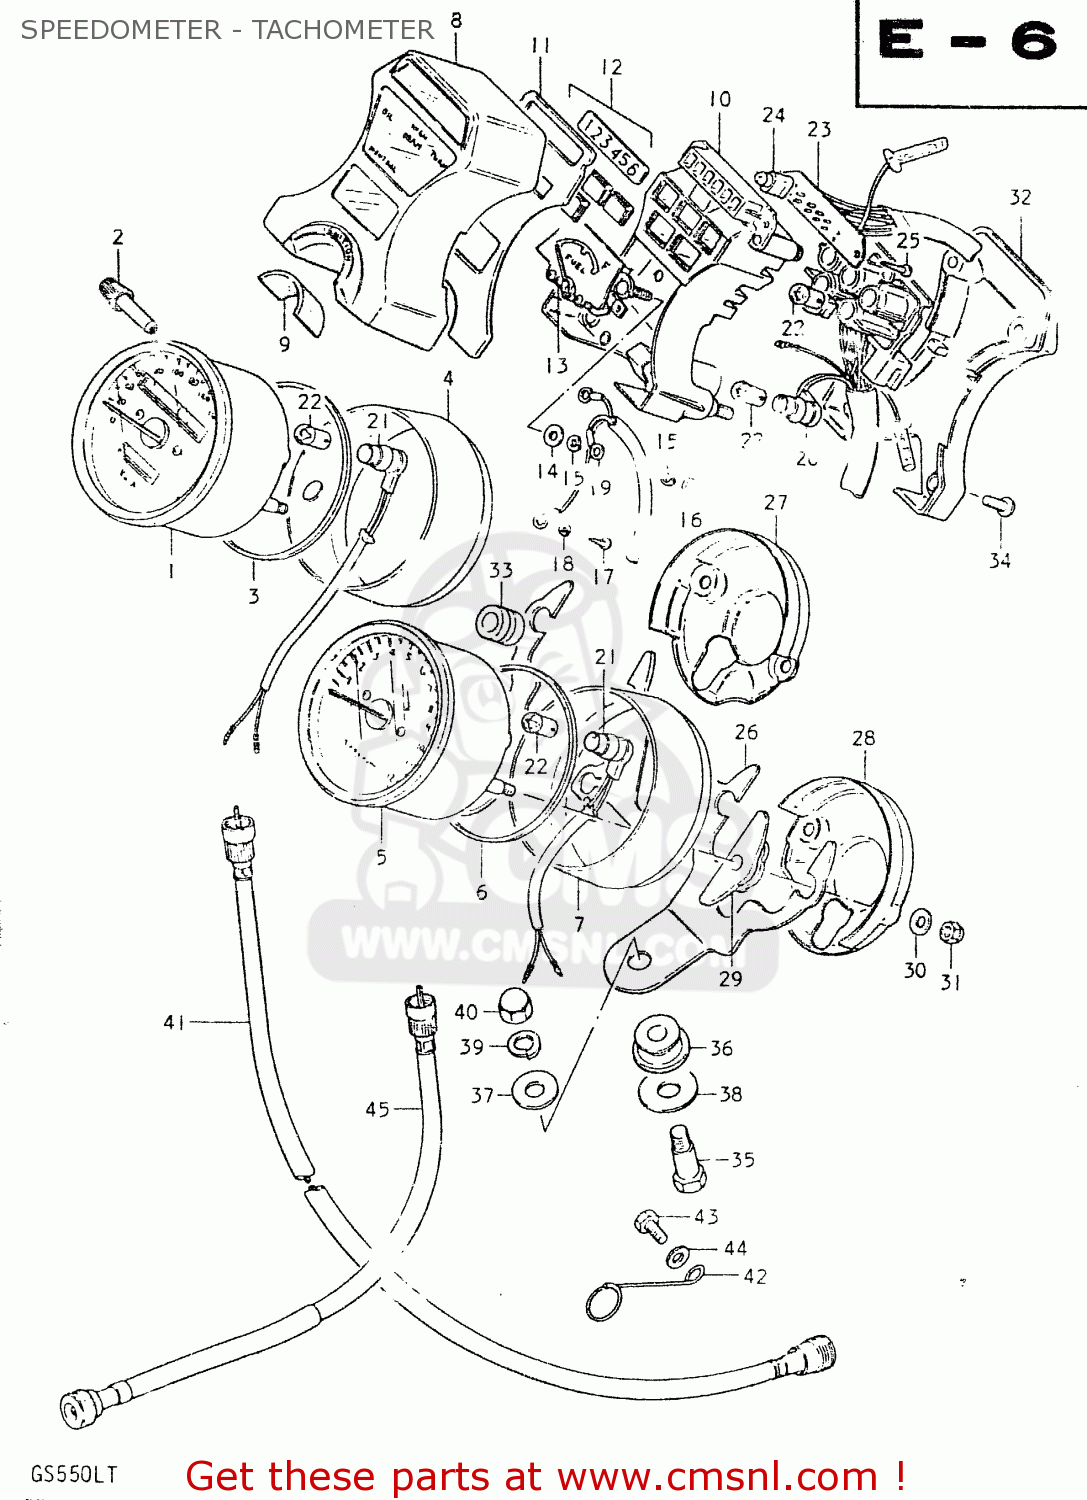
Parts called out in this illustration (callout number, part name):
1	SPEEDOMETER
2	KNOB
3	CUSHION
4	COVER,SPEEDOMETER
5	TACH0METER
6	CUSHION
7	COVER,TACHOMETER
8	CASE,PILOT BOX,OUTER
9	SEAL,IGNITION SWITCH
10	CASE, PILOT BOX INNER
11	PLATE,PILOT BOX
12	LENS SET,PILOT
13	METER,FUEL
14	WASHER
15	LOCK WASHER
16	NUT
17	SCREW
18	LOCK WASHER
19	LEAD WIRE, FUELMETER
20	SOCKET
21	SOCKET,METER
22	BULB(12V3.4W,STANLEY,A72A)
23	INDICATOR ASSEMBLY,GEAR POSITION
24	BULB(14V1.12W)
25	SCREW
26	BRACKET,COMBINATION METER
27	ORNAMENT,SPEEDOMETER
28	COVER,TACHOMETER
29	CUSHION,METER
30	WASHER
31	NUT
32	COVER,PILOT BOX,UNDER
33	CUSHION,PILOT BOX
34	SCREW,PILOT BOX
35	BOLT(8X31)
36	CUSHION,METER
37	WASHER(8.5X23X1.2)
38	WASHER
39	LOCK WASHER
40	NUT
41	CABLE ASSEMBLY,SPEEDOMETER
42	GUIDE,SPEEDOMETER CABLE
43	BOLT, UPPER
44	WASHER
45	CABLE ASSEMBLY,TACHOMETER
